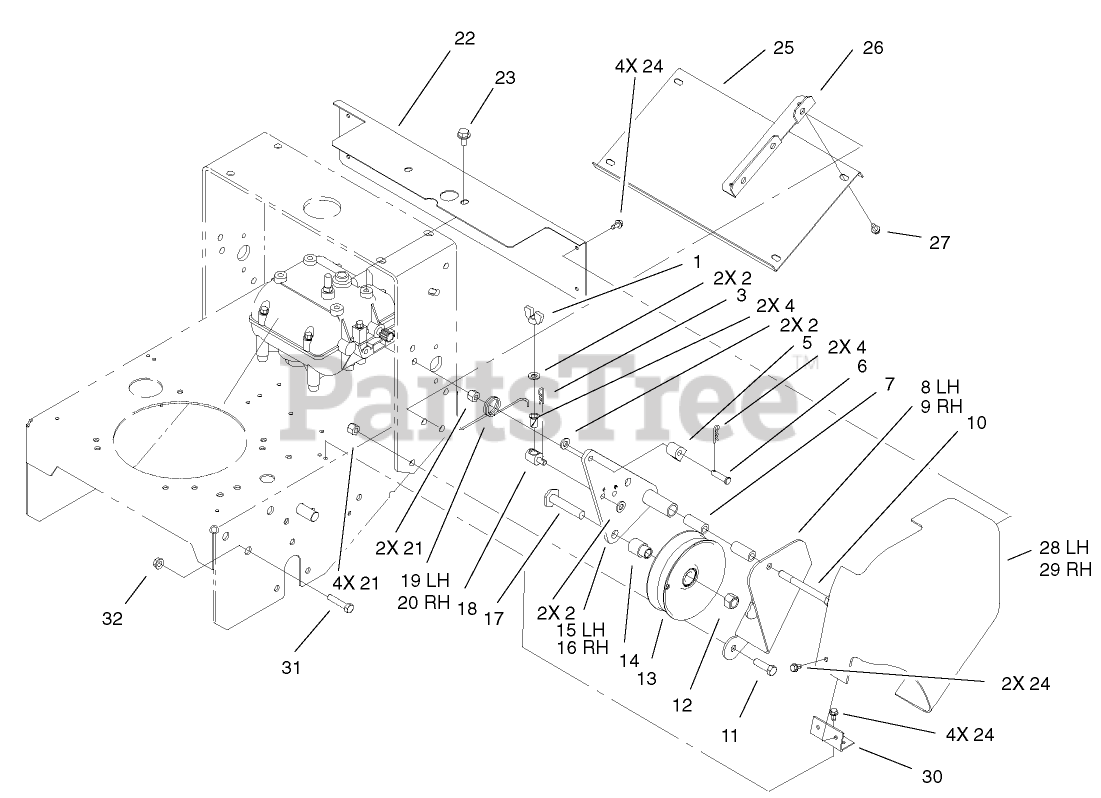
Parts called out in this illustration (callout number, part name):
1	NUT-WING
2	WASHER-PLAIN
3	PIN-COTTER
4	BUSHING-NYLON
5	FITTING-ROD
6	PIN-CLEVIS
7	SPACER-PIVOT, IDLER
8	BRACKET-SUPPORT, LH
9	BRACKET-SUPPORT, RH
10	SCREW-HH
11	SCREW-HH
12	NUT-LOCK, NI
13	PULLEY-IDLER
14	SPACER-PULLEY
15	BRACKET-IDLER, LH
16	BRACKET-IDLER, RH
17	SCREW-LEVELER
18	FITTING-ROD
19	SPRING-TORSION, LH
20	SPRING-TORSION, RH
21	NUT-LOCK, NI
22	GUARD-SHAFT, TRANSMISSION
23	SCREW-HWHTF
24	SCREW
25	PANEL-BOTTOM
26	ANGLE-MOUNTING
27	SCREW
28	Guard-Belt, LH
29	Guard-Belt, RH
30	MOUNT-BELT GUARD
31	SCREW-HHF
32	NUT-HF
